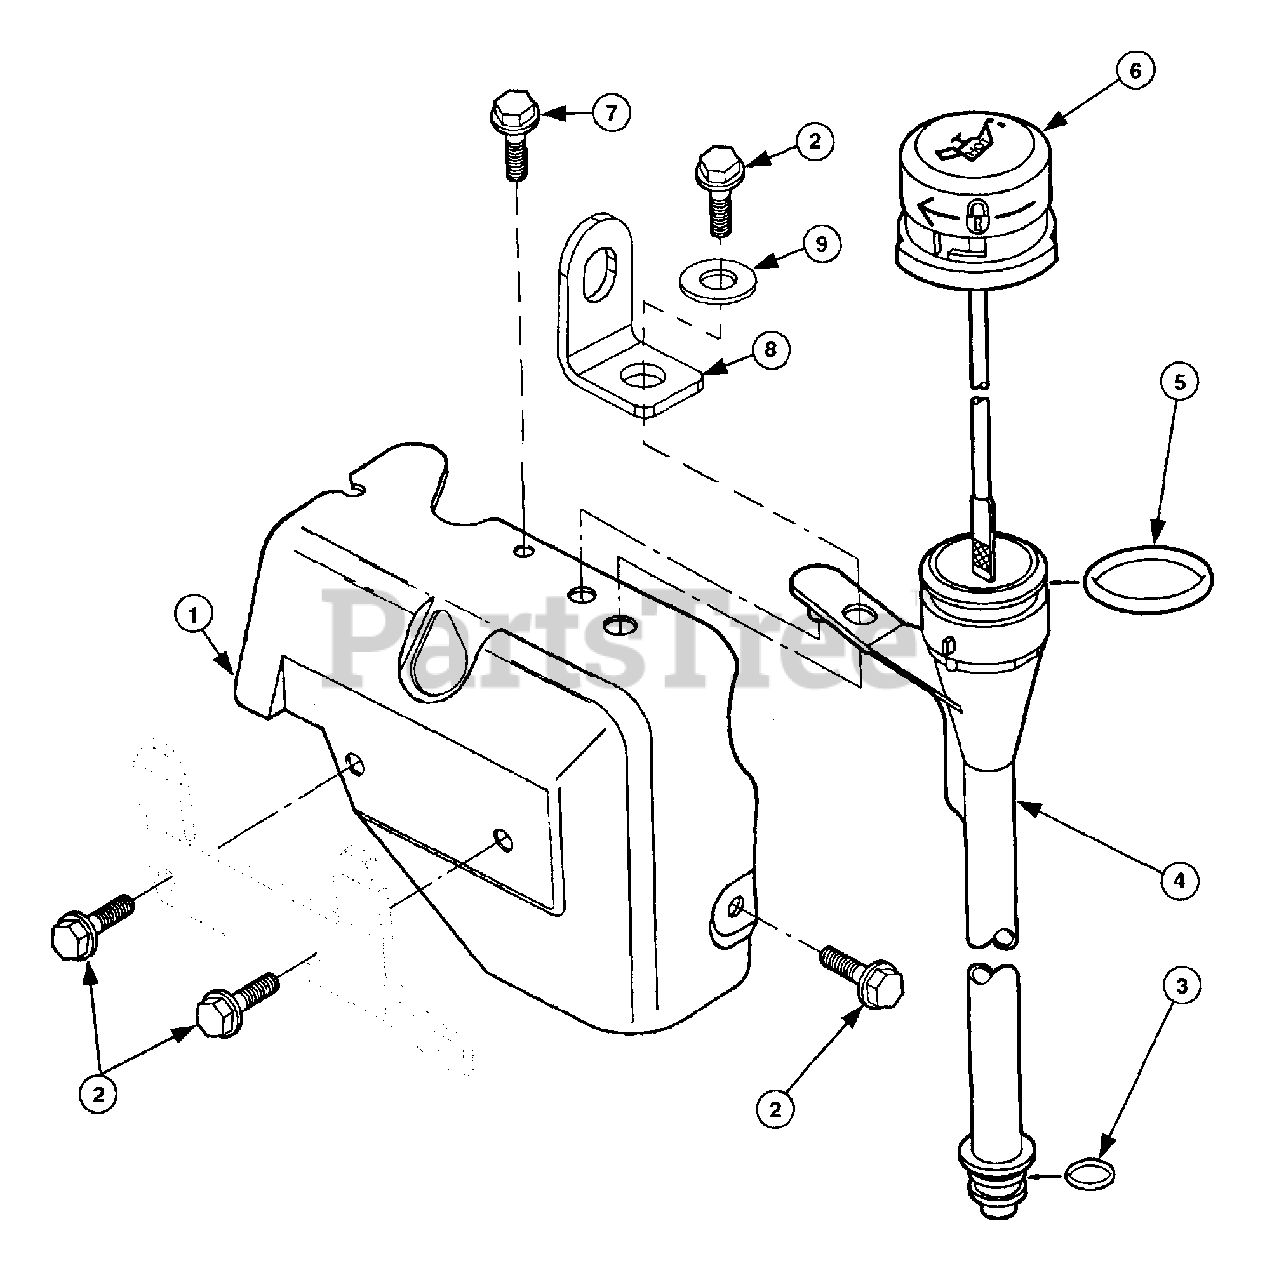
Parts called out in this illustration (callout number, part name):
1	Housing, Air Cylinder
2	Screw, Hx Hd TT, M8 x 1.25 x 16
3	O-Ring, Lower
4	Tube, Oil Fill
5	O-Ring, Upper
6	Indicator and Cap Ass'y.
7	Screw, Hx Flange Lock, M6 x 1 x 16
8	Bracket, Lift
9	Washer, Flat, 5/16"
